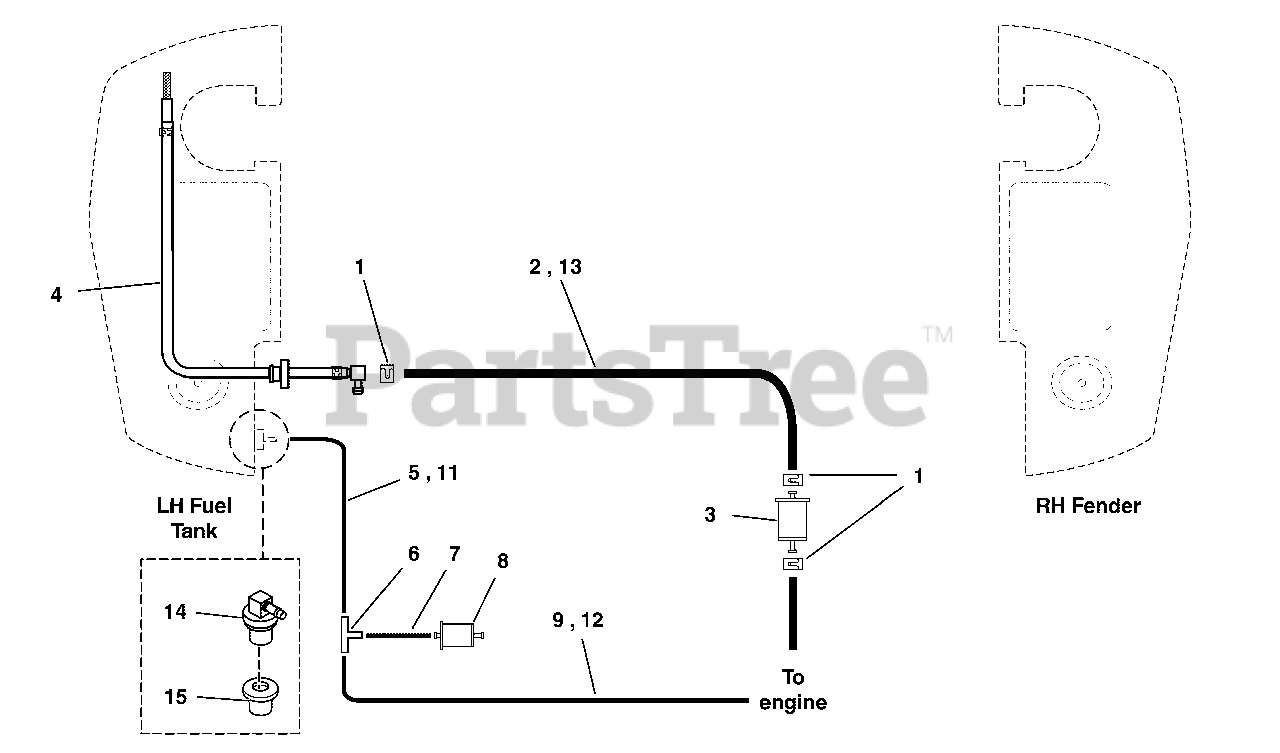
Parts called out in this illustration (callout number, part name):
1	CLAMP, Hose
2	HOSE, 1/4" FUEL, 14.00"
3	FUEL FILTER (SV)
4	ASSM, FUEL HOSE, 26
5	HOSE, VAPOR, 5MM ID, 34.00 LG
6	FITTING, 3/16" TEE, BARB TYPE, HDPE
7	HOSE, VAPOR, 5MM ID, 2.00 LG
8	FILTER, Fuel
9	HOSE, VAPOR, 5MM ID, 9.00 LG
11	HOSE, VAPOR, 5MM ID 21.50 LG
12	HOSE, VAPOR, 5MM ID 21.50 LG
13	HOSE, 1/4" FUEL, 24.00"
14	REMOTE VENT ASSEMBLY
15	GROMMET
